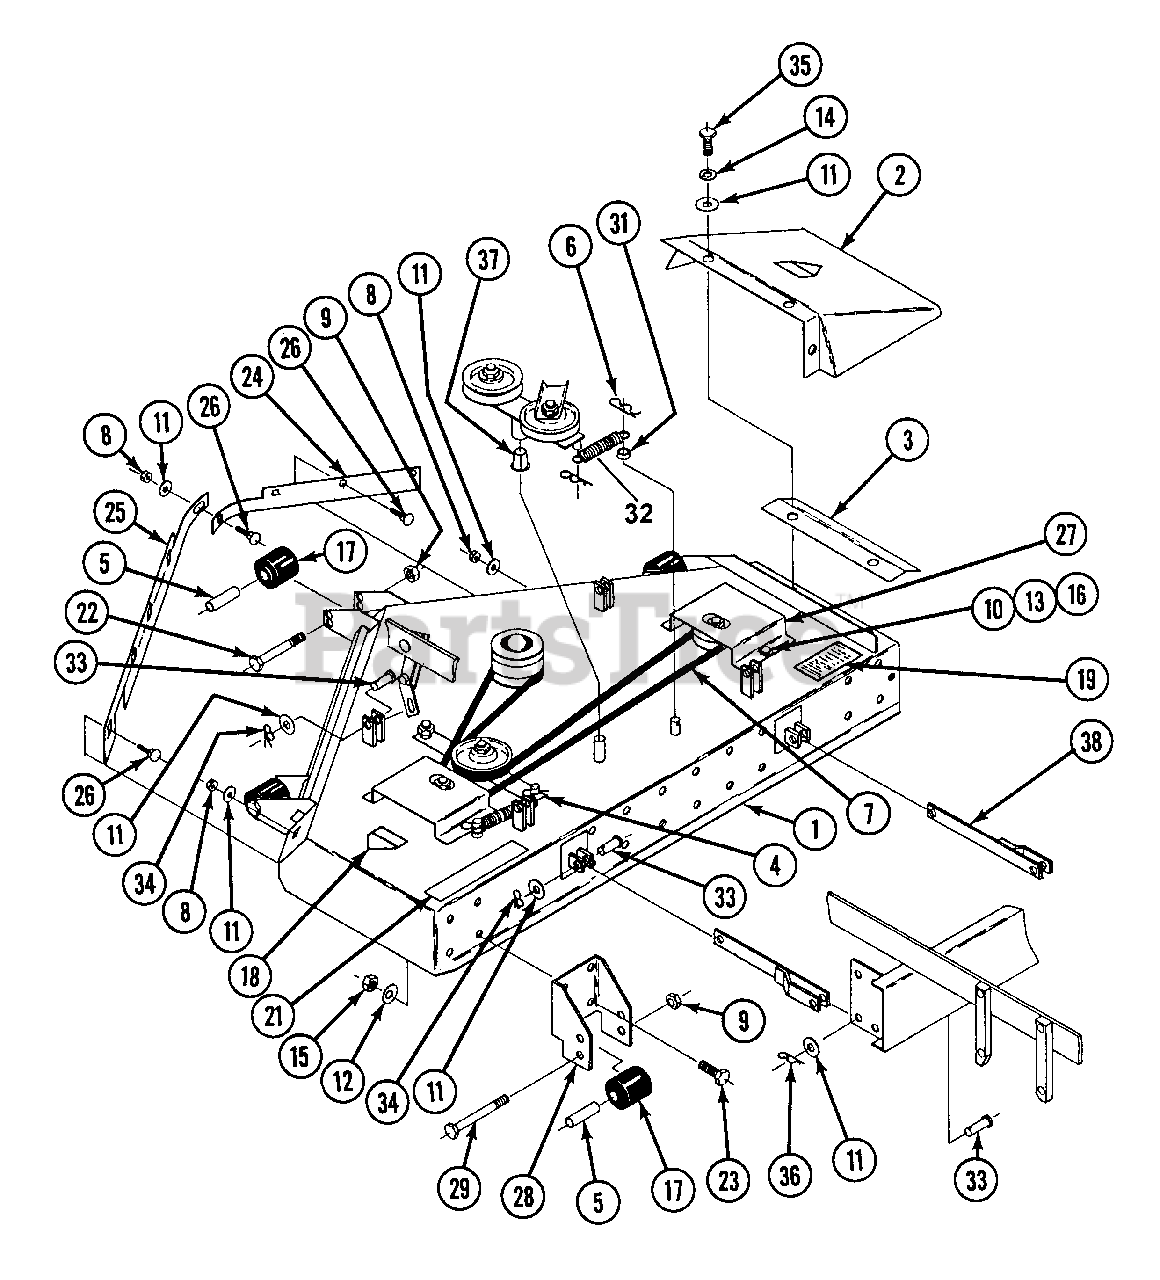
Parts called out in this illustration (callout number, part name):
1	DECK WELDMENT
2	DECK CHUTE ASSEMBLY
3	CHUTE DEFLECTOR
4	SINGLE IDLER ASSEMBLY
5	ROLLER SPACER BUSHING
6	PIN, HAIR SPRING: 1/8 X 2-1/2
7	DECK BELT, AP105
8	LOCKNUT, NYLOCK: 5/16-18
9	LOCKNUT, STOVER: 3/8-16
10	FLAT WASHER, STD: 1/4
11	FLAT WASHER, STD: 5/16
12	FLAT WASHER, STD: 3/8
13	LOCKWASHER, SPLT SPRNG: 1/4
14	LOCKWASHER, SPLT SPRNG: 5/16
15	LOCKNUT, NYLOCK: 3/8-16
16	CAPSCREW, HX HD: 1/4-20 X 3/4 GR5
17	ROLLER, LOW DENSITY POLYETHYLENE
18	DECAL, BLOODY STUMP
19	DECAL, "WARNING ALL DECKS..."
21	DECAL, "4800"
22	CAPSCREW, HX HD: 3/8-16 X 5 GR 5
23	CAPSCREW, HX HD: 3/8-16 X 7/8 GR 5
24	LIP BAFFLE, RH
25	LIP BAFFLE, LH
26	BOLT, CARRIAGE: 5/16-18 X 3/4
27	PULLEY COVER
28	REAR ANTI-SCALP BRACKET
29	CAPSCREW, HX HD: 3/8-16 X 4-1/2 GR 5
31	SPACER, DECK SPRING
32	SPRING, EXTENSION
33	PIN, CLEVIS: 5/16 X 1-1/4
34	COTTER, RUE RING: 5/16-3/8 PIN
35	CAPSCREW, HX HD: 5/16-18 X 3/4 GR 5
36	PIN, HAIR SPRING: .080 X 9/16
38	DRAG BAR WELDMENT
